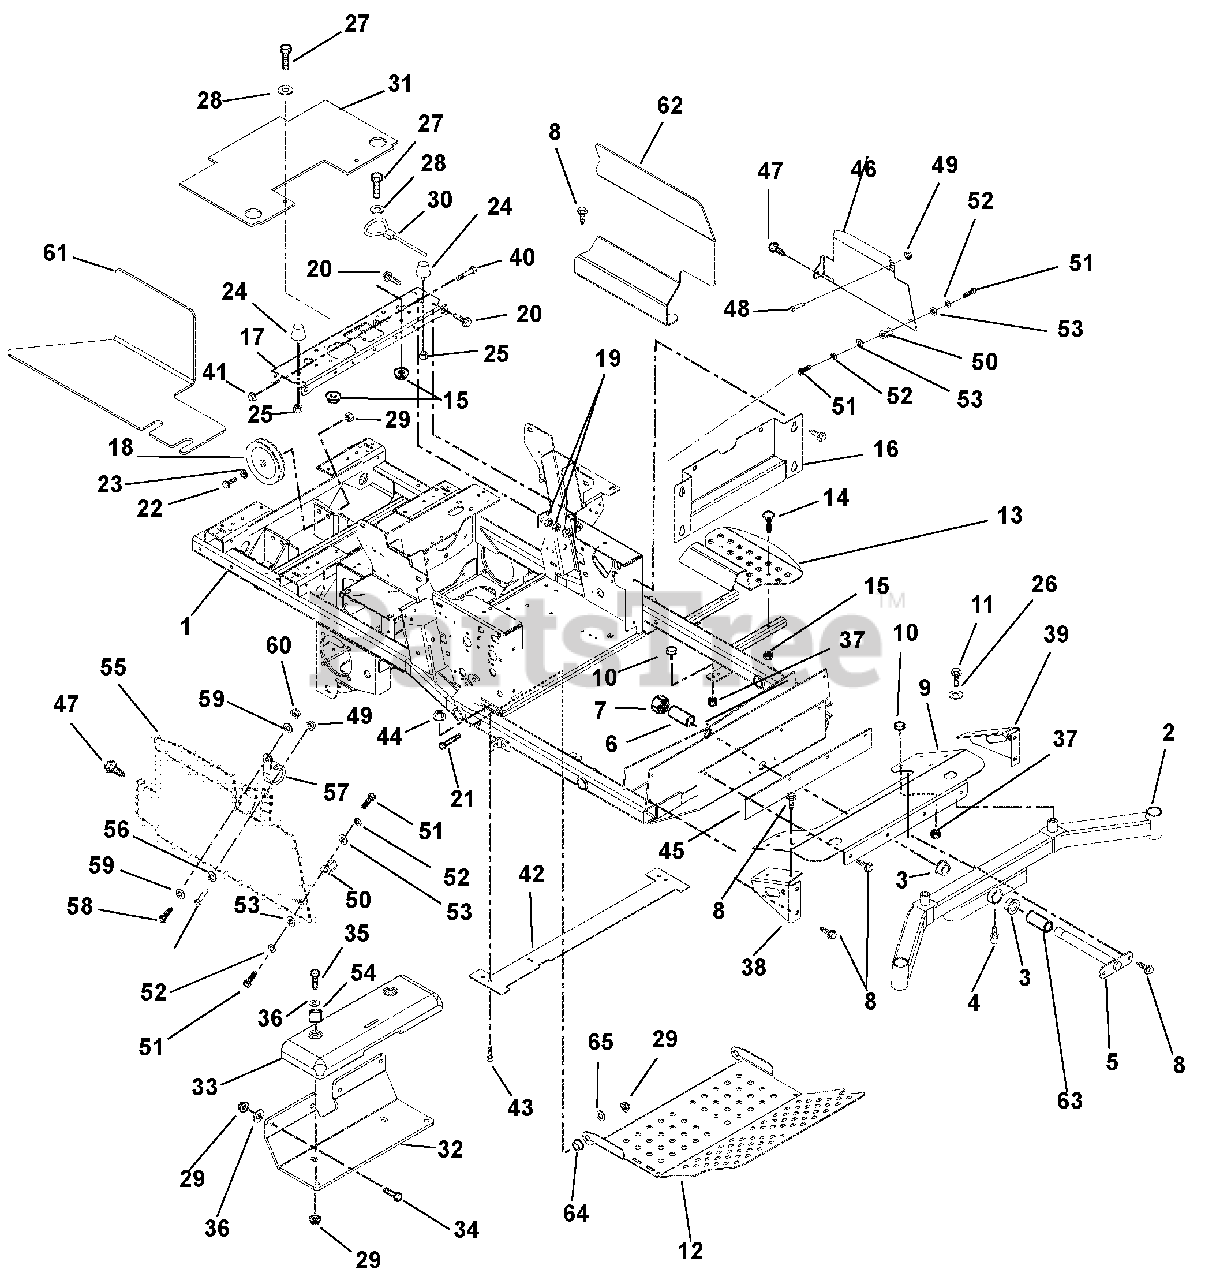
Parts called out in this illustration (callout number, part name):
1	Weldment, Frame
2	Weldment, Front Axle
3	Bushing, Flange 1.25 x 1.50 x 1.00 x 2.00
4	Fitting, Lube 45 Degree GM411031
5	Pin, Axle
7	Nut, Locking Nylon 1.0-14
8	Screw, Tapping .38-16 x .75
9	Axle Cover
10	Button, Bumper
11	Bolt, Hex .50-20 x 1.00 Grade 5
12	Panel, Inspection
13	Step, Ingress
14	Bolt, Round Head Square Neck .31-18 x 1.75 Grade 5
15	Nut, Locking Top Flange .31-18
16	Plate, Kick
17	Channel, Cross
18	Pulley, Idler
19	Nut, Retainer .375-16 x .37
20	Bolt, Serrated Flange Washer Head .38-16 x 1.00
21	Bolt, Hex .50-13 x 3.25 Grade 5
22	Bolt, Hex .50-13 x 2.25 Grade 5
23	Washer, Flat Steel .505 x .88 x .072
25	Nut, Spin Lock Flange .312-18
26	Washer, Flat Steel .060 x 1.75 x .250
27	Bolt, Hex .31-18 x 1.00 Grade 5
28	Washer, Flat Steel .344 x 1.125 x .135
29	Nut, Locking Top Flange .50-13
30	Cable, Seat Prop
31	Guard, Grass
32	Bracket, Weight (992316, 317, 321, 322)
33	Weight, Cast Iron
34	Bolt, Hex .50-13 x 1.25 Grade 5
35	Bolt, Hex .50-13 x 4.50 Grade 5
36	Washer, Flat Steel .531 x 1.06 x .095
37	Nut, Spin Lock, Flange .312-18
38	Weldment, Axle Cover Support Right Hand
39	Weldment, Axle Cover Support Left Hand
40	Bolt, Hex .38-16 x 3.00 Grade 5
41	Nut, Locking Top Flange .38-16
42	Plate, Switch
43	Bolt, Hex .31-18 x .75 Grade 5
44	Nut, Locking Top Flange .31-18 YWZC
45	Plate, Backer
46	Plate, Guard, Debris (992324)
47	Screw, Tapping Hex Washer Head .38-16 x .50 TR (992324)
48	Bolt, Hex Washer Head .25-20 x .75 Grade 5 (992324)
49	Nut, Nylock, Flanged, .25-20 (992324)
50	Nut, Coupling .31-18 x 2.25 LG (992324)
51	Bolt, Hex .31-18 x .75 Gr 5 (992324)
52	Washer, Locking .31 x .078 Reg (992324)
53	Washer, Flange Steel .344 x .688 x .065 (992324)
54	Spacer, .563 x 6.25 x .969 (992324)
55	Bracket, Guard Right Hand (992324)
56	Washer, Plated, Steel (992324)
57	Clamp, Steel (992324)
58	Bolt, .38-16 x 1.25 Grade 5 (992324)
59	Washer, Flat Steel .406 x .812 x .065 (992324)
60	Nut, Locking Top Flange .38-16 (992324)
61	Guard, Diesel Left Hand (992324)
62	Guard, Diesel Right Hand (992324)
63	Spacer 1.25 O. x 1.00 I. x 3.63 (992324)
64	Bushing, Flange .515 x .75 x .275
65	Washer, Flat Steel .563 x 1.38 x .109
